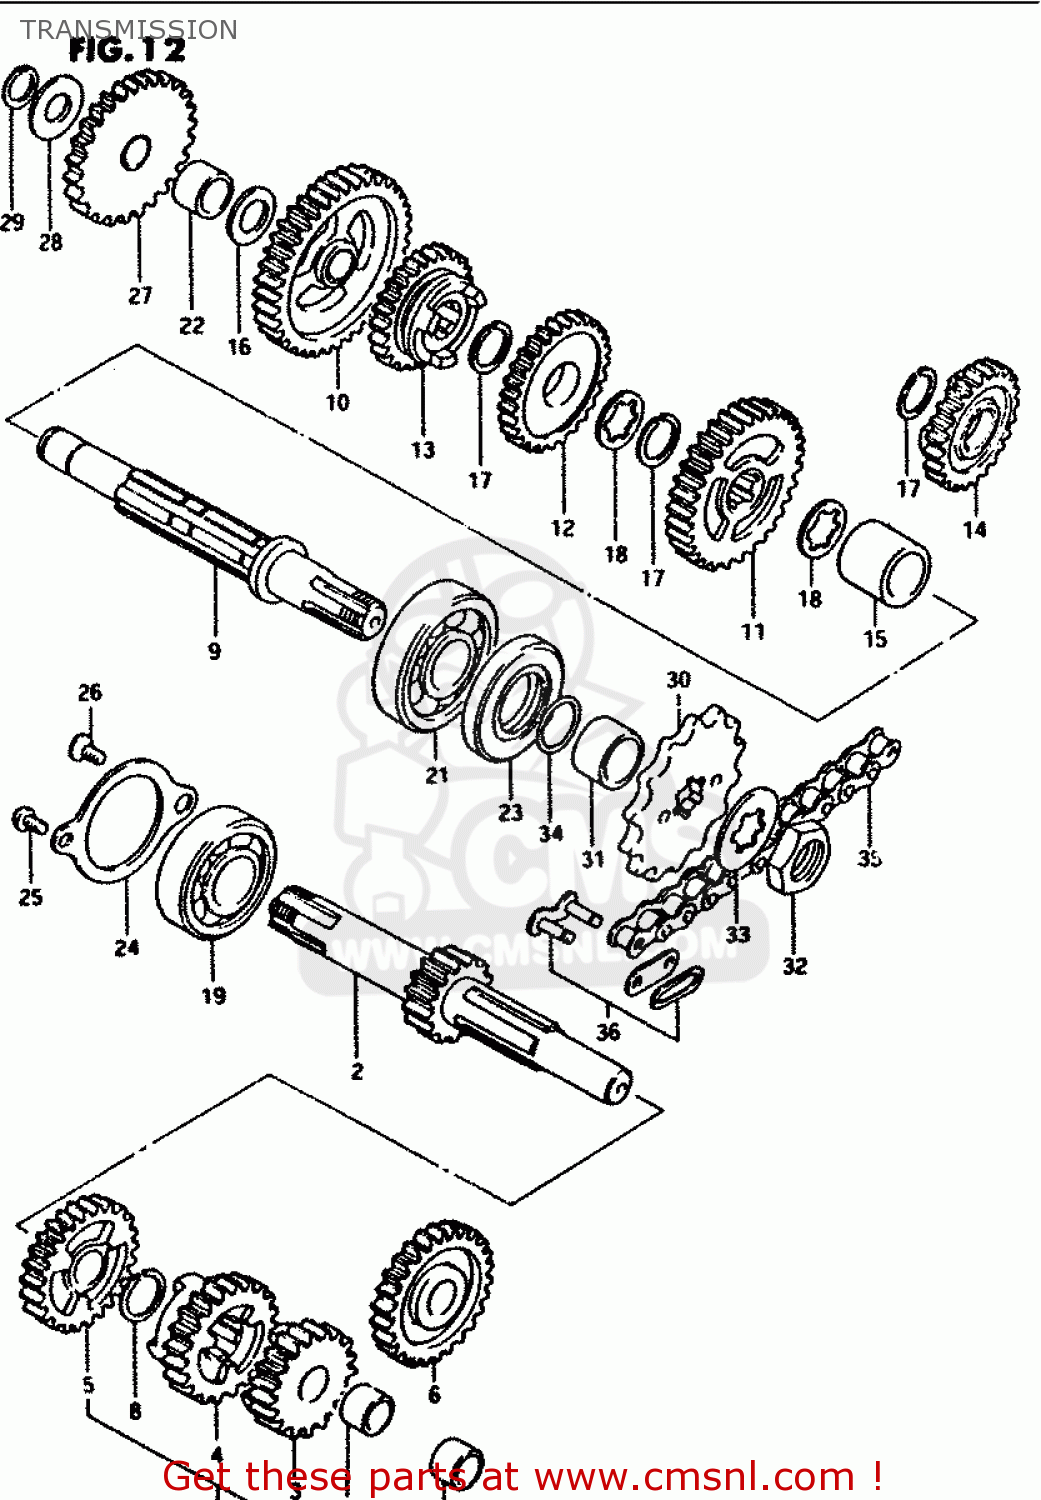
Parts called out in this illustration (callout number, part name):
1	SHAFT,COUNTER
2	SHAFT,COUNTER(NT:12)
3	GEAR,SECOND DRIVE
4	GEAR,3RD DRIVE
5	GEAR,4TH DRIVE(NT:24)
6	GEAR,FIFTH DRIVE
7	SPACER
8	CIRCLIP
9	SHAFT,DRIVE
10	GEAR,1ST DRIVEN
11	GEAR,2ND DRIVEN(NT:33)
12	GEAR,3RD DRIVEN(NT:29)
13	GEAR,FOURTH DRIVEN
14	GEAR,5TH DRIVEN(NT:24)
15	SPACER
16	WASHER(13X24X1)
17	CIRCLIP
18	WASHER,LOCK
19	BEARING(17X40X12)
20	BUSH
21	BEARING
22	BUSH
23	SEAL,OIL(21X40X6)
24	RETAINER,CNTR SHAFT BEARING
25	SCREW
26	SCREW
27	GEAR,KICK STARTER IDLE
28	WASHER
29	CIRCLIP,12 MM
30	SPROCKET,ENGINE(NT:14)
31	SPACER(17X21X13)
32	NUT
33	WASHER,LOCK
34	O RING(D:1,ID:16.8)
35	CHAIN ASSEMBLY,DRIVE
36	JOINT
